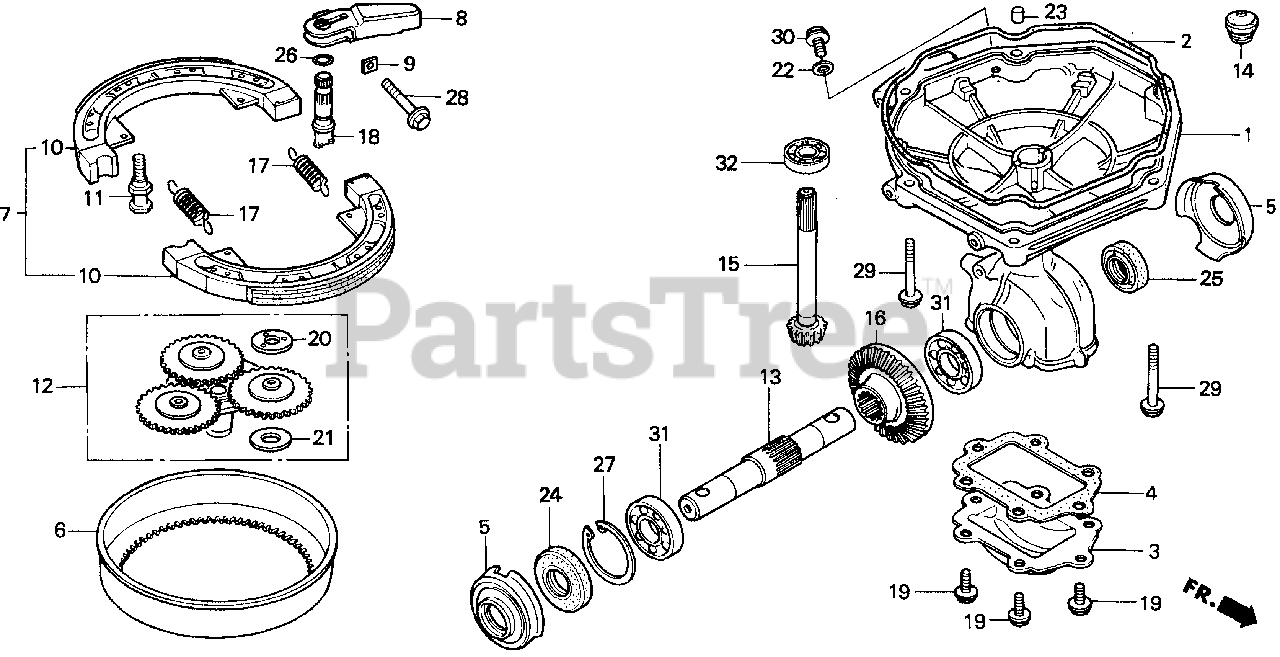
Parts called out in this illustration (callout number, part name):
1	CASE, REDUCTION
2	O-RING (208MM)
3	COVER (LOWER)
4	GASKET, COVER (LOWER)
5	GUARD, GRASS
6	CLUTCH (OUTER)
7	SHOE SET, CLUTCH
8	ARM, CLUTCH
9	PLATE, ARM LOCK
10	SHOE SET, CLUTCH
11	PIN, ANCHOR
12	PLATE, DRIVE
13	SHAFT, TINE
14	CAP, TRANSMISSION OIL
15	PINION, BEVEL (12T)
16	GEAR, BEVEL (37T)
17	SPRING, FR. BRAKE SHOE
18	CAM, CLUTCH
19	BOLT, SPECIAL (6X14)
20	WASHER (8MM)
21	WASHER A, THRUST (12MM) (0.8)
21	WASHER B, THRUST (12MM) (1.0)
21	WASHER C, THRUST (12MM) (0.7)
22	WASHER (10.5MM)
23	PIN, DOWEL (8X12)
24	OIL SEAL (20X47X7)
25	DUST SEAL (20X40X11)
26	O-RING (8.8X1.9)
27	CIRCLIP (INNER) (47MM)
28	BOLT, FLANGE (6X32)
29	BOLT, FLANGE (6X45)
30	BOLT, FLANGE (10X16)
31	BEARING, RADIAL BALL (6204)
32	BEARING, RADIAL BALL (6302)
